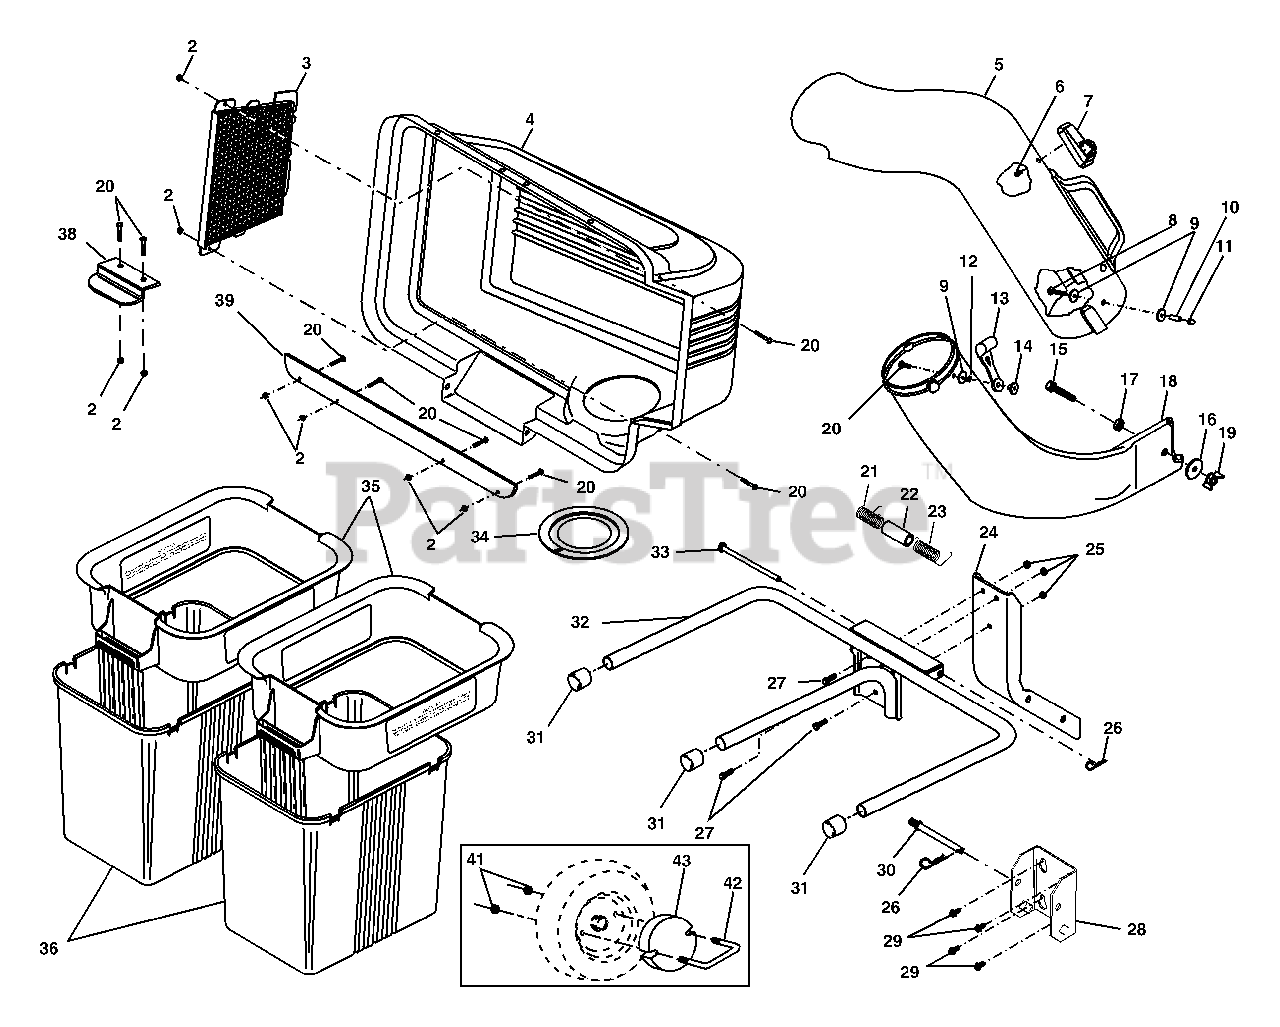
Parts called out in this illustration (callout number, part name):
2	Nut, Crownlock #10-24
3	Screen, Cover
4	Cover Assembly
6	Screw, Special
7	Dump Bag Indicator
8	Screw, #10-24 x 1-1/8
9	Washer 3/16x3/4x16 Ga.
10	Spacer, Split
11	Nut, Acorn #10-24
14	Nut, Weld
15	Bolt, Hex 3/8-16 x 1-1/4
16	Washer 13/32x1x16 Ga.
17	Locknut 3/8-16
19	Wingnut 3/8-16
20	Screw #10-24 x 5/8
21	Spring, Cover L.H. (black)
22	Spacer, Cover
23	Spring, Cover R.H. (gray)
24	Post, Support
25	Locknut 5/16 x 18
26	Spring, Retainer
27	Carriage Bolt, 5/16-18 x 3/4
28	Bracket, Mounting
29	Shoulder Bolt
30	Pin, Support Post
31	Plug, Tubing End
32	Bagger, Frame
33	Pin, Hinge
34	Gasket, Cover
35	Container, Top
36	Container, Bottom
38	Latch Handle, Cover
39	Strip, Reinforcement
41	Locknut 3/8-16
